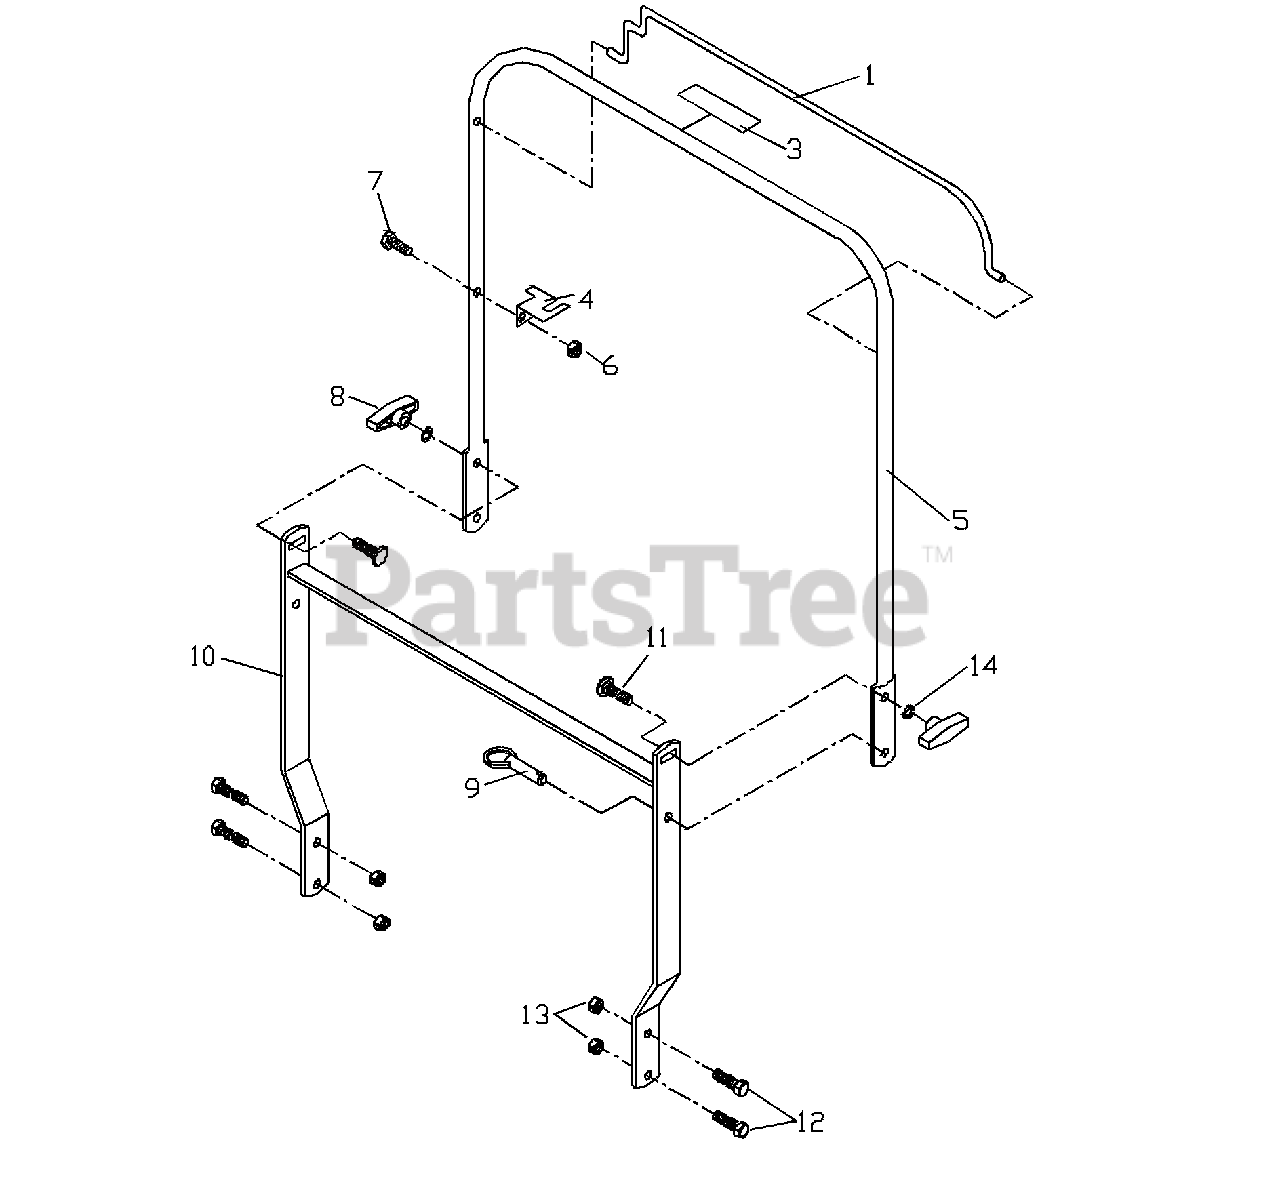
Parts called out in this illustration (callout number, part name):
1	CLUTCH BAIL
3	CLUTCH CONTROL DECAL
4	CABLE MOUNTING BRACKET
5	UPPER HANDLE
6	1/4-20 NYLOC NUT
7	1/4-20 X 1-1/2 HCS
9	DETENT PIN ASSEMBLY
10	LOWER HANDLE
11	5/16-18 X 1-1/4 CARRIAGE BOLT
12	3/8-16 X 1 HCS
13	3/8-16 NYLOC NUT
14	5/16 LOCK WASHER
